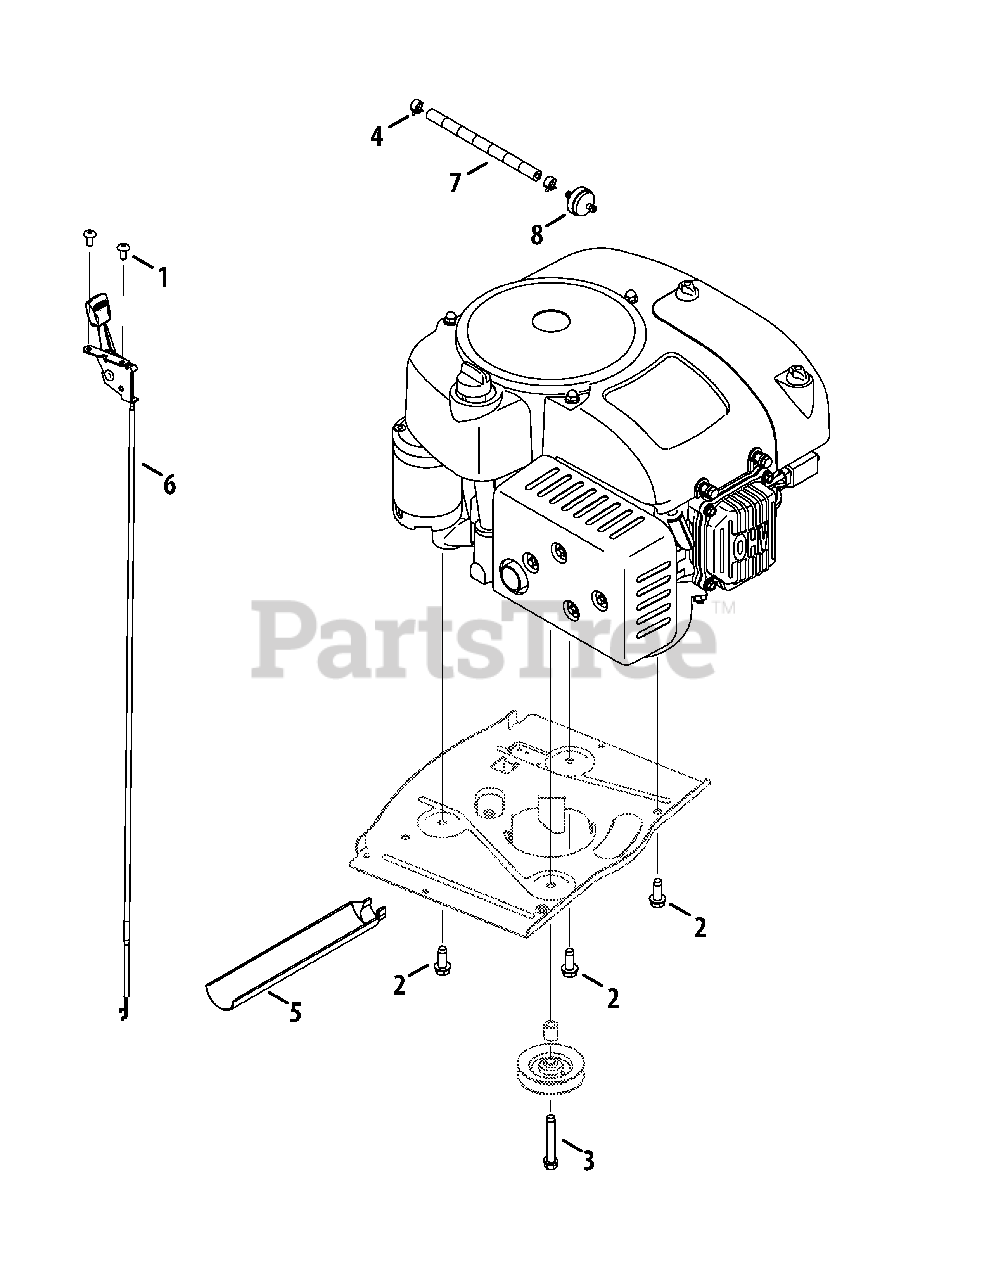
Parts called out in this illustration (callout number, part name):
1	Tap Screw, 1/4-20, 0.500
2	Tap Screw, 3/8-16, 1.000
3	Tap Screw, 3/8-16, 2.250
4	Hose Clamp, .490 DIA.
5	Oil Drain Sleeve
6	Throttle/Choke Cable 31 Lg.
7	Low Permeation Fuel Line, 1/4
8	Fuel Filter
